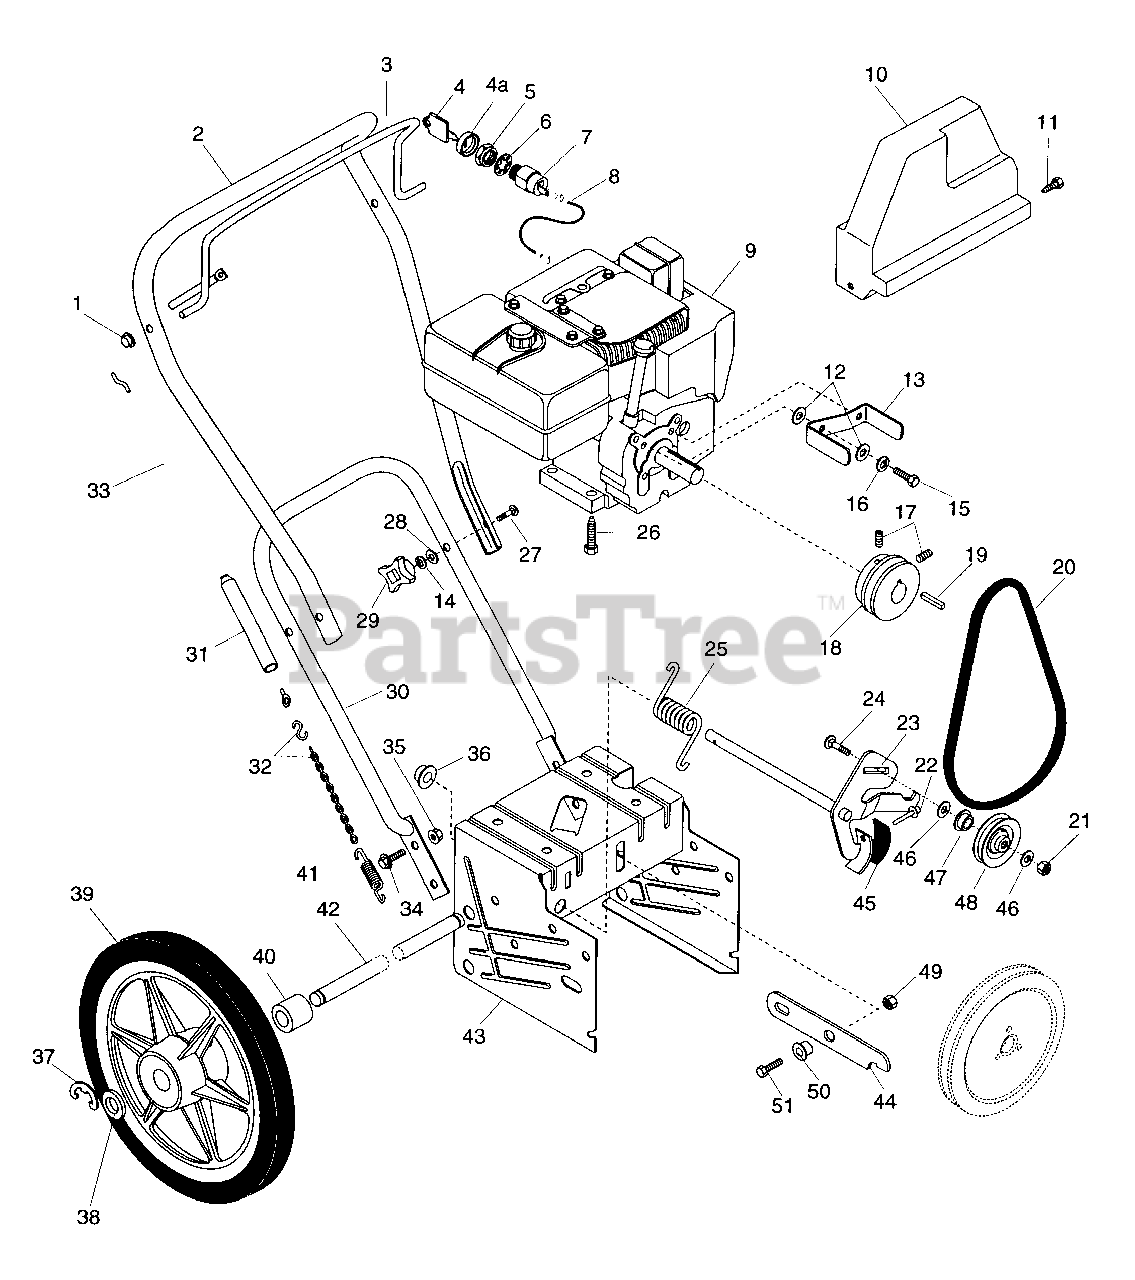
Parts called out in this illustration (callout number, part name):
1	NUT-PUSH .312 DIA. PAL
2	UPPER HANDLEBAR
3	BAIL
4	KEY -W/CAP
4A	CAP - IGNITION SWITCH
5	NUT .625-32 ALUM
6	WSHR-LK-INT .625X.045 PL
7	SWITCH
8	WIRE
9	ENGINE-HSSK 50 TEC NO PTO
10	BELT COVER
11	SCR-TAP .250-20X.37 HWH PL TR
12	WSHR-FL-STL .380X.875X.179 PL
13	BELT FINGER
14	WSHR-LK .312X.097 PL HVY
15	BLT-HEX .31-24X.75 PL GR5
16	WSHR-LK .313X.093 MED HICLR
17	SCR-SET .31-18X.38 SKHCUPDL
18	ENGINE SHEAVE
19	KEY-SQ .188X1.0X.188 SAE 8630
20	V-BELT, 4L-COGGED
21	NUT-LK .312-18 GR A PL
22	RVT-TBLR .187X.437 RH ST PL
23	BRAKE CLUTCH ARM W/LINING
24	BLT-RDHDSQNK .31-18X1.38SHT PL
25	SG-TORS .148X1.0X1.53
26	SCR-TAP .375-16X1.0 HWH PL TR
27	BLT-CRVD-HD .31-18X3.0 PL
28	WSHR-FL-STL .323X.625X.062 PL
29	KNOB 5/16-18 UNC
30	LOWER HANDLEBAR
32	CHAIN & CONNECTOR
34	BLT-SERHFWH .31-18X.62 PL
35	NUT-FLG. .312-18 PL
36	CAP, .50 ROD YWZC
37	RG-RTNG-EXT .500X.042 (E)
38	WSHR-FL-STL .505X.880X.072 PL
39	WHEEL - 16 X 1.75 X .562
40	AXLE SPACER
41	SG-TENS .091X.56X4.25 WLD 40
44	ARM
45	BRAKE LINING
46	WSHR-FL-STL .38X.875X.083 PL
47	SPCR, BRG .315X.50X.688X.281
48	IDLER
49	NUT-LK-CTR .250-20 PL
50	BSHG-FLG .265X.437X.250X.750
51	BLT-HEX .25-20X.63 PL GR2
